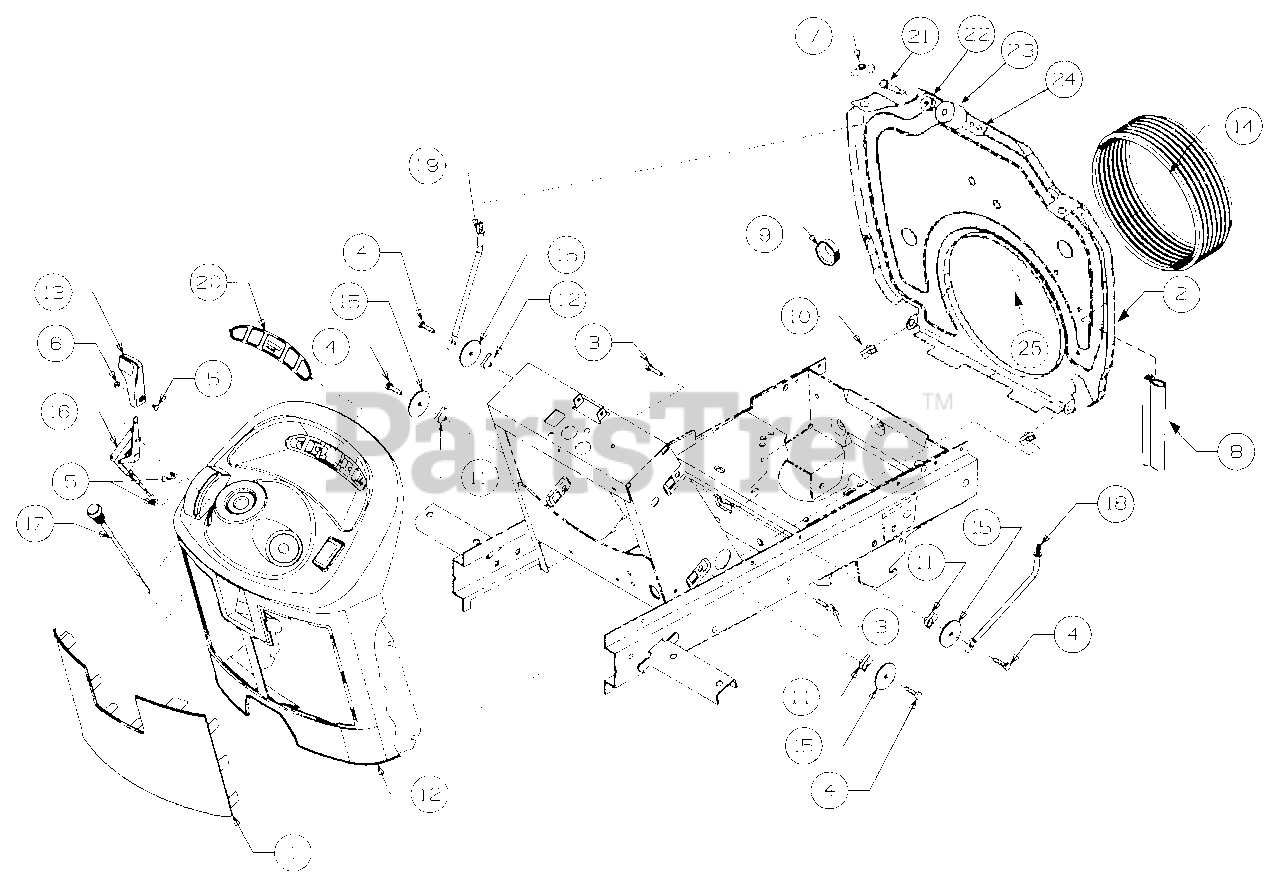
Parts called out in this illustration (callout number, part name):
4	Screw, Hex Cap, 1/4-20 x 1.0
5	Screw, Cross Rec Trus, #8-32 x .38
6	Nut, #8-32
7	Nut, Wing w/Bell Washer 1/4-20
8	Seal, Push On Trim
9	Bushing, Snap, 7/8 ID
10	Nut, U-Type Speed, 1/4-20
11	Nut, U-Clip, 1/4-20
12	Panel, Dash
13	Knob, Throttle
14	Boot, Intake
15	Washer, Flat, .285 x 1.75 x .10
16	Control, Throttle
17	Control, Choke
18	Rod, RH Mounting
19	Rod, LH Mounting
20	Label, Dash
21	Screw, Hex Cap,1/4-20 x 1.75 GR5
22	Washer, Flat, .283 x .75 x .030
23	Roller, Hood Latch
24	Nut, Hex Sems, 1/4-20
25	Plug. Button
